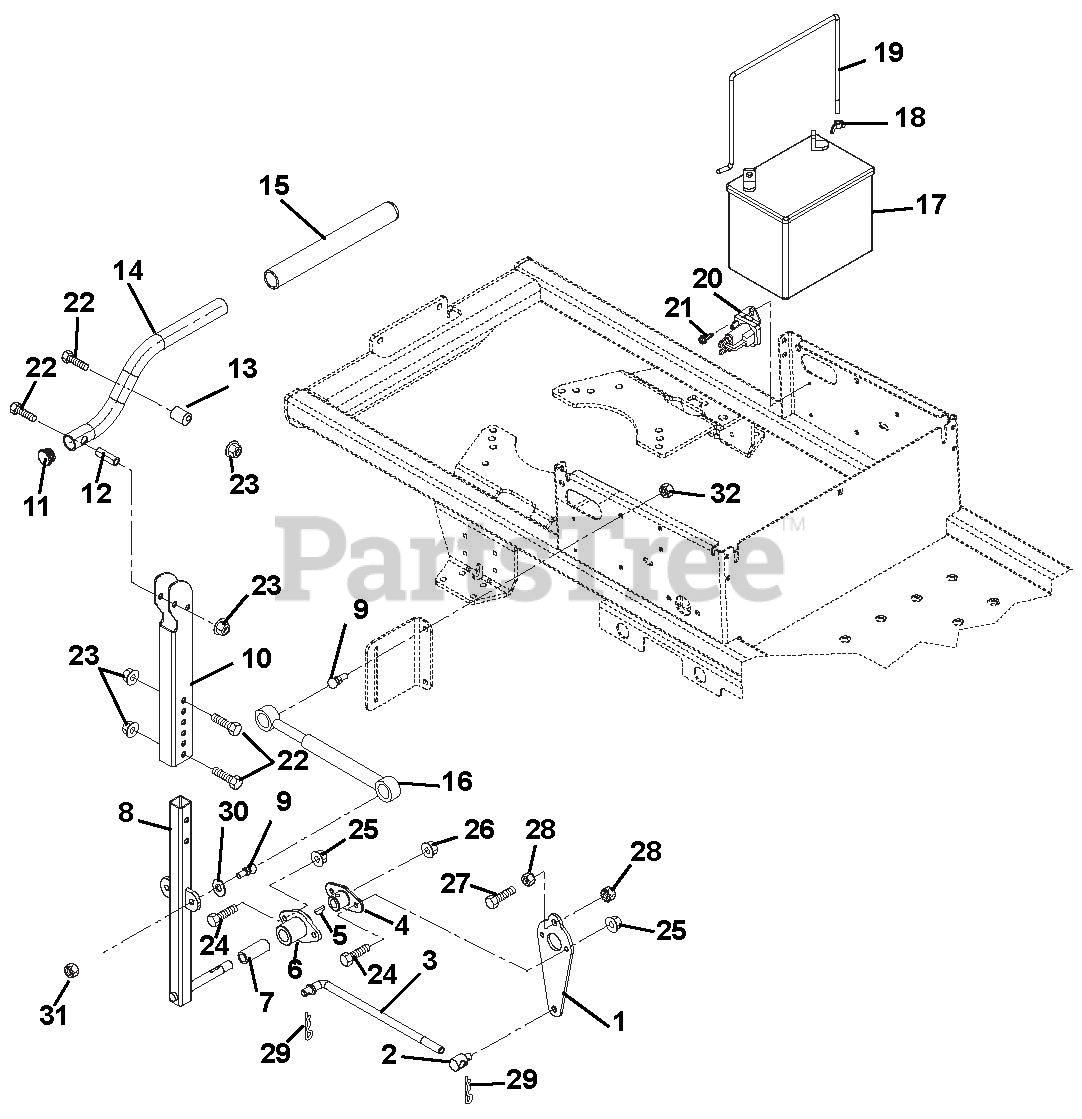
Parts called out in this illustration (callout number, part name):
1	LINK,CONTROL
2	PIVOT, ROD (TRUNNION ) .50
3	LINK,WIREFORM
4	ARM, SPEED CONTROL
5	KEY-WDRF .125X.75
6	BUSHING,FLANGED
7	BUSHING,1/2X3/4X1-7/8LG
8	WMT,LOWER HANDLEBAR
9	STUD- BALL
10	CHANNEL,UPPER HANDLEBAR
11	CAPLUG, HANDLEBAR
12	BSHG, SPCR .330X.500X1.01 PM
13	BSHG,ECCEN .328X.750X1.01 PM
14	HANDLE BAR
15	GRIP - HANDLEBAR
16	DAMPER, CONTROL
17	BATTERY, 300 CCA 10U1L
18	NUT-LK WING .250-20 YWZC
19	BATTERY ROD
20	SOLENOID
21	@SCR-TAP .25-20X.37 HWH YWZ TR
22	@BLT-HEX .31-18X1.75 GR5 YWZC
23	@NUT-LK-NYL-FLG .31-18 YWZC
24	@BLT-HEX .25-20X.75 GR5 YWZC
25	@NUT-LK-TOP-FLG .25-20 YWZC
26	@NUT-LK-TOP-FLG .50-13 YWZC
27	@BLT-HEX .38-16X1.75 GR5 YWZC
28	@NUT-SPNLK-FLG .375-16 YWZC
29	PIN-HAIR, ENDRIES #25 YWZC
30	@WSHR-LK .31X.078 REG YWZC
31	NUT- JAM .312-18 YWZC
32	@NUT-LK-TOP-FLG .31-18 YWZC
